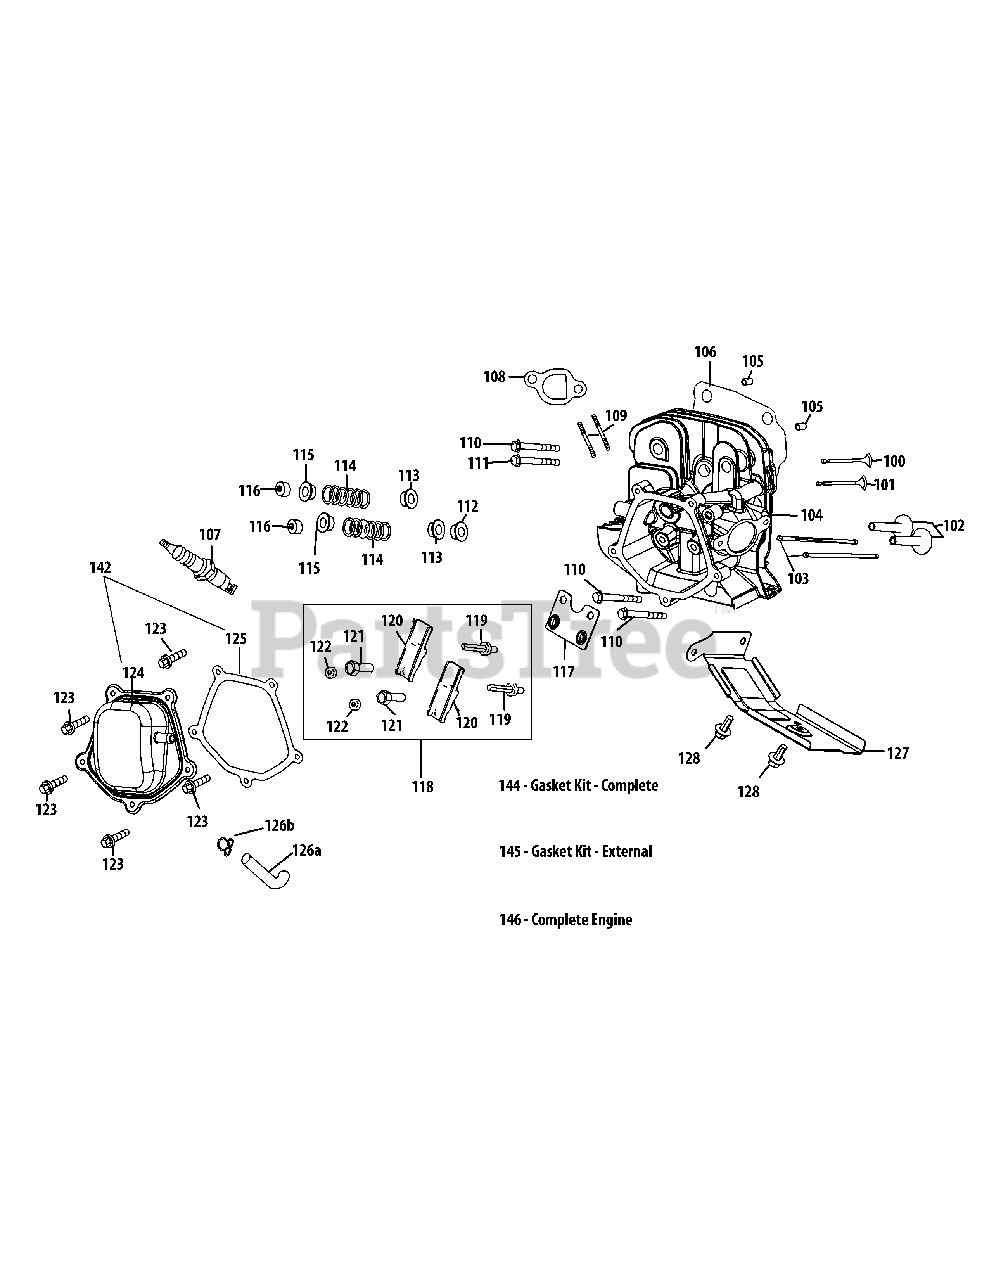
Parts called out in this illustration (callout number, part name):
100	Valve Kit
101	Valve Kit
102	Tappet
103	Push Rod Kit
104	Cylinder Head Kit
104	Cylinder Head Assembly
105	Dowel Pin
106	Cylinder Head Gasket
107	Spark Plug/F6Rtc
108	Muffler Gasket
109	Exhaust Stud M8×48.5
109	Muffler Stud Assembly
110	Bolt M10×1.25×87
111	Bolt M10×1.25×65
112	Intake Valve Seal
113	Intake Valve Spring Retainer
114	Valve Spring
115	Exhaust Valve Spring Retainer
116	Exhaust Lash Cap
117	Push Rod Guide
118	Rocker Arm Assembly
119	Bolt, Pivot
120	Rocker Arm
121	Adjusting Nut ,Valve
122	Pivot Locking Nut
123	Valve Cover Bolt
124	Valve Cover
125	Valve Cover Gasket
127	Cylinder Baffle
128	Bolt M6×12
142	Valve Cover Kit
144	Gasket Kit - Complete
145	Gasket Kit - External
146	Complete Engine
